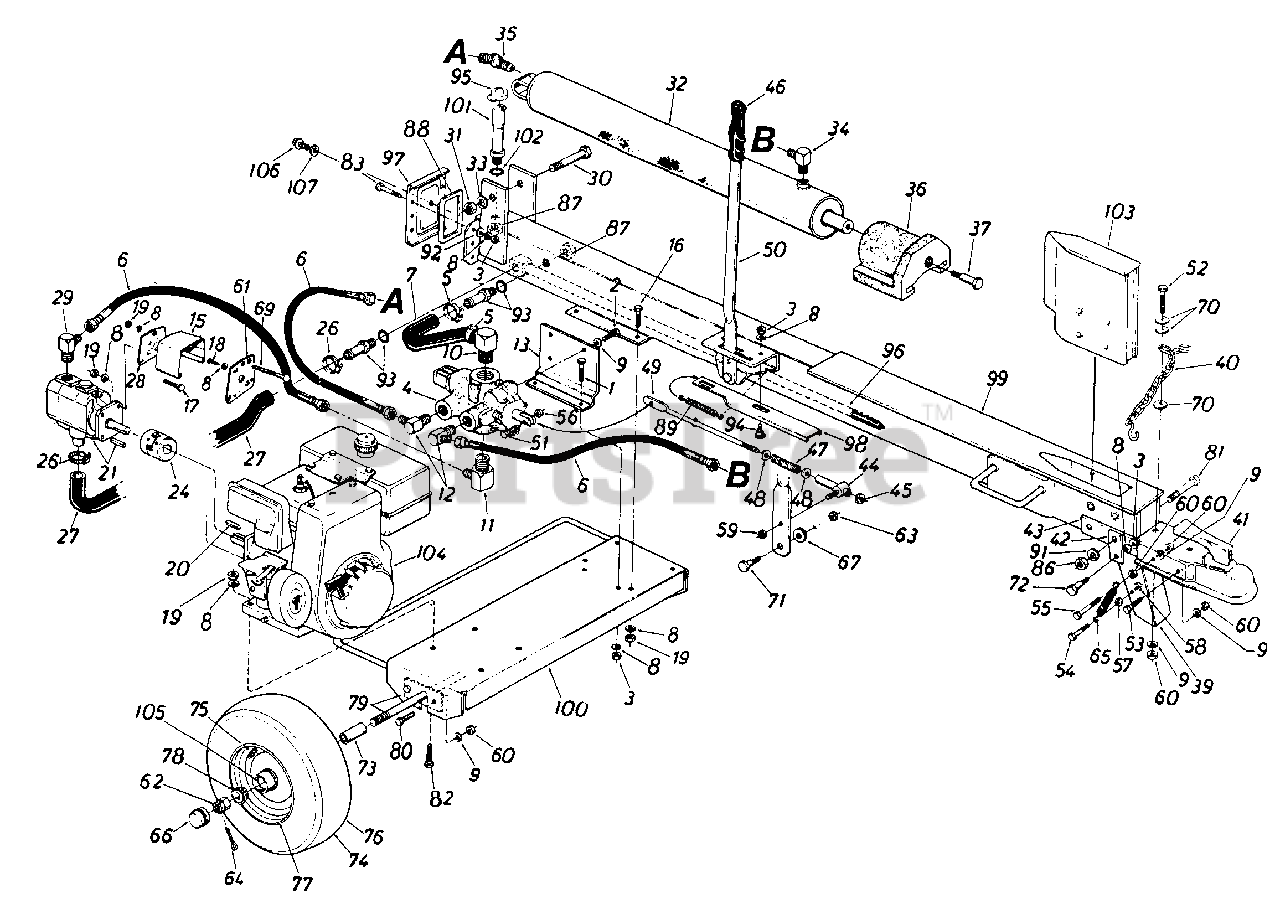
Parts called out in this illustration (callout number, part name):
1	SCREW-HEX 5/16-18 X .75
2	SCREW-HEX 3/8-16 X .50
3	NUT-HEX 5/16-18
4	VALVE-CONTROL
5	CLAMP-HOSE-5/8
6	HOSE ASSY-PRESSURE
7	HOSE-RETURN
8	WASHER-LOCK-5/16
9	WASHER-LOCK-3/8
10	ELBOW-RETURN
11	ADAPTER-90 DEGREE
12	ADAPTER-90 DEGREE
13	PLATE-MTG-VALVE
15	SHIELD-COUPLING
16	SCREW-HEX SPECIAL 5/16-24X1.0
17	SCREW-HEX 5/16-24 X .75
18	SCREW-HEX 5/16-24 X .62
19	NUT-5/16-24
20	KEY-SQ 3/16X2.25
21	PUMP
24	COUPLING-FLEX-COMP
26	CLAMP-HOSE-5/8
27	HOSE ASSY-SUCTION
29	ADAPTER-90 DEGREE
30	SCREW-HEX 3/4X4.0
31	NUT-HEX 3/4
32	CYLINDER-HYDRO
33	WASHER
34	ADAPTER-90 DEGREE
36	PLATE-PUSH
37	SCREW-SHLD .62X.475
39	BRACKET-FLIP STAND
40	CHAIN-TOW HITCH
41	HITCH ASSY-TOW
42	BRACKET-PIVOT
43	BRACKET-TOW HITCH
44	FERRULE ASSY
45	NUT-HEX INS L 3/8 X 24
46	GRIP-LIFT HANDLE
47	SPRING-BRAKE
48	WASHER-SPEC .378 X 1.00 X .125
49	ROD-ENGAGEMENT
50	HANDLE-ENGAGEMENT
51	SCREW-HEX 1/4-20 X 1.25
52	SCREW 3/8-24X1.25 GR5
53	SCREW-HEX 3/8-24 X .75
54	SCREW-HEX 1/4-28 X 1.00
55	SCREW-HEX 3/8-24 X 1.75
56	NUT-HEX CENTER L-1/4-20
57	NUT-HEX CENTER L-1/4-28
58	NUT-HEX 1/4-28
59	NUT-HEX CENTER L-5/16-18
60	NUT-HEX 3/8-24
62	NUT-HEX CASTLE
63	NUT-HEX CENTER L-3/8-16
64	PIN-COTTER-5/32 DIA
65	SPRING-EXTENSION
67	WASHER-RUBBER .50 X 1.00 X .25
69	SCREW-HEX 5/16-24 X 4.00
70	WASHER-FL-.385 ID X .87 OD X .06
71	SCREW-SHLD .498 DIA X .340
72	SCREW-SHLD .437 DIA X .265
75	VALVE-TUBELESS AIR
76	TIRE-PNEU 16.0X4.0
78	BEARING-ROLLER-3/4 IN
79	AXLE ASSY
80	BOLT-3/8 NF X 1"GR5
81	SCREW-HEX 5/8-18 X 3.50
82	SCREW-HEX 5/16-24 X 1.75
83	SCREW-HEX 5/16-18 X 1.50
86	NUT-HEX 5/8-18
87	NUT-HEX 1 1/16-12
89	SPRING-EXTENSION
91	WASHER-LOCK-5/8
92	WASHER-FL (#46041)
94	SCREW-SHLD .437 DIA X .180
95	CAP ASSY-GAS
96	TUBE ASSY-STRAINER
97	PLATE-END
98	BRACKET-ENGAGE
99	TANK ASSY
100	FRAME ASSY
101	TUBE ASSY-FILLER
103	WEDGE ASSY
105	RETAINER-GREASE
106	SCREW-HEX WASH HD 5/16-18
107	WASHER-GASKET
